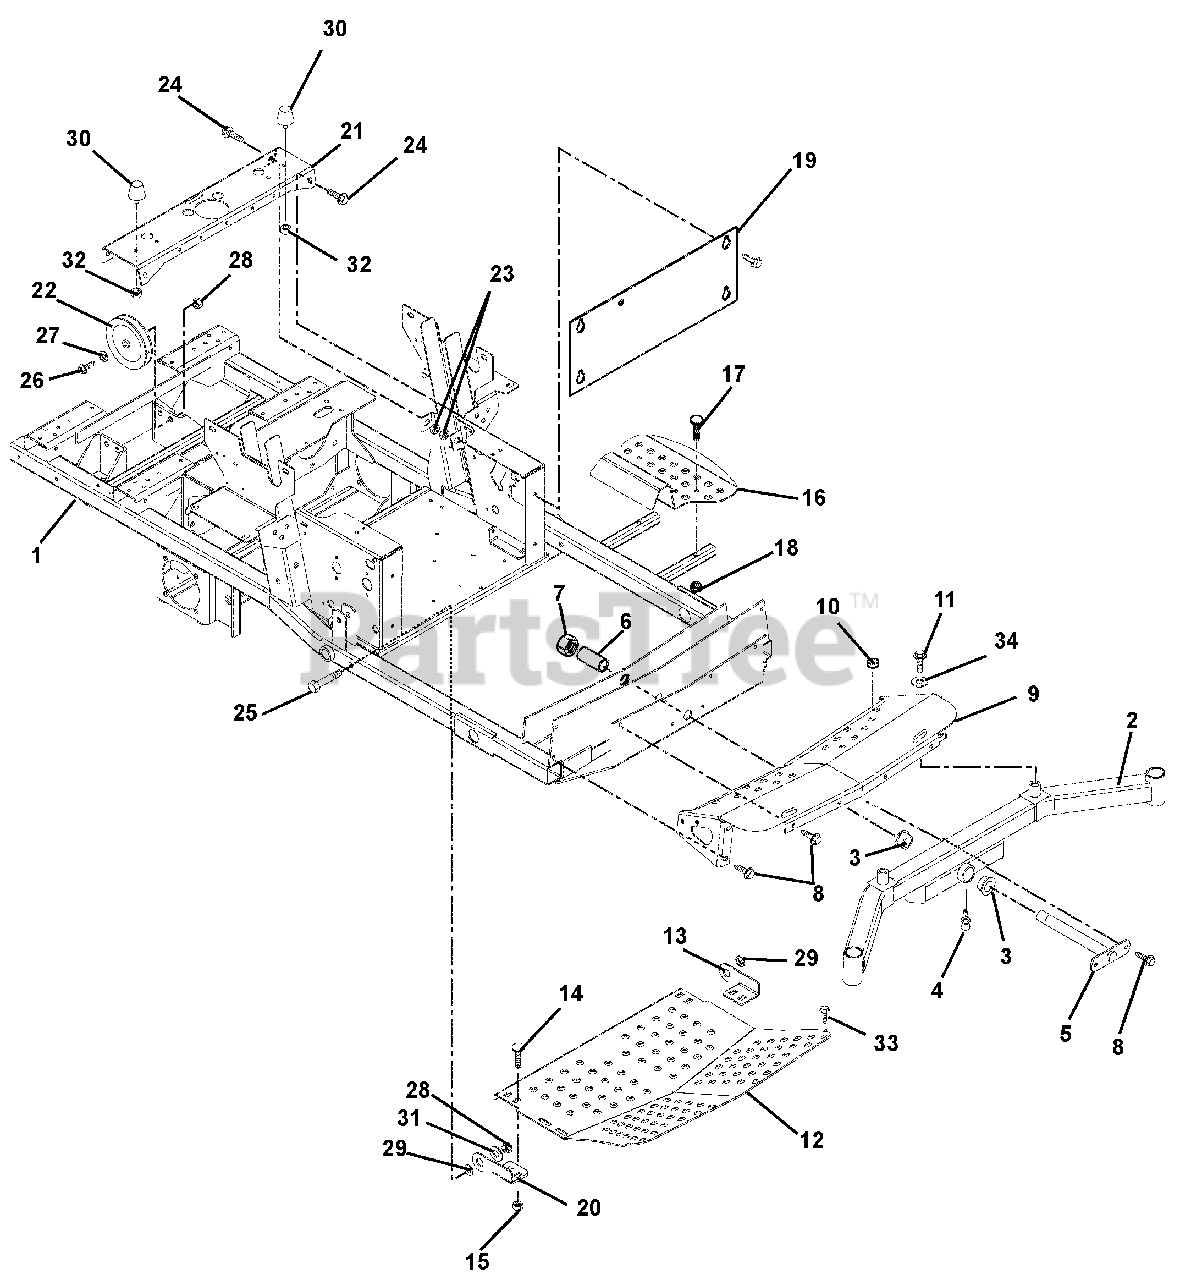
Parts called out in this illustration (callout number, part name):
1	Weldment, Frame
2	Weldment, Front Axle
3	Bushing, Flange 1.020 x 1.385 x .75 x 1.75
4	Fitting, Lube .25-28 x .256
5	Pin, Axle
7	Nut, Locking Nylon 1.0-14
8	Screw, Tapping .38-16 x .75
9	Weldment, Axle Cover
10	Button, Bumper
11	Bolt, Hex .50-20 x 1.00 Grade 5
12	Panel, Inspection
13	Hinge, Footboard Left Hand
14	Bolt, Round Head Square Neck .38-16 x 1.00 Grade 5
15	Nut, Locking Top Flange .38-16
16	Step, Ingress
17	Bolt, Round Head Square Neck .31-18 x 1.75 Grade 5
18	Nut, Locking Top Flange .31-18
19	Plate, Kick
20	Hinge, Footboard Right Hand
21	Channel, Cross
22	Pulley, Idler
23	Nut, Retainer .375-16 x .37
24	Bolt, Serrated Flange Washer Head .38-16 x 1.00
25	Bolt, Hex .50-13 x 3.25 Grade 5
26	Bolt, Hex .50-13 x 2.25 Grade 5
27	Washer, Flat Steel .505 x .88 x .072
28	Nut, Locking Top Flange .50-13
29	Bushing, Flange .515 x .75 x .275 x 1.12
31	Washer, Flat Steel .563 x 1.38 x .109
32	Nut, Locking Flange .312-24
33	Screw, Tapping Hex Washer Head .38-16 x 1.00
34	Washer, Flat Steel .518 x 2.00 x .105
